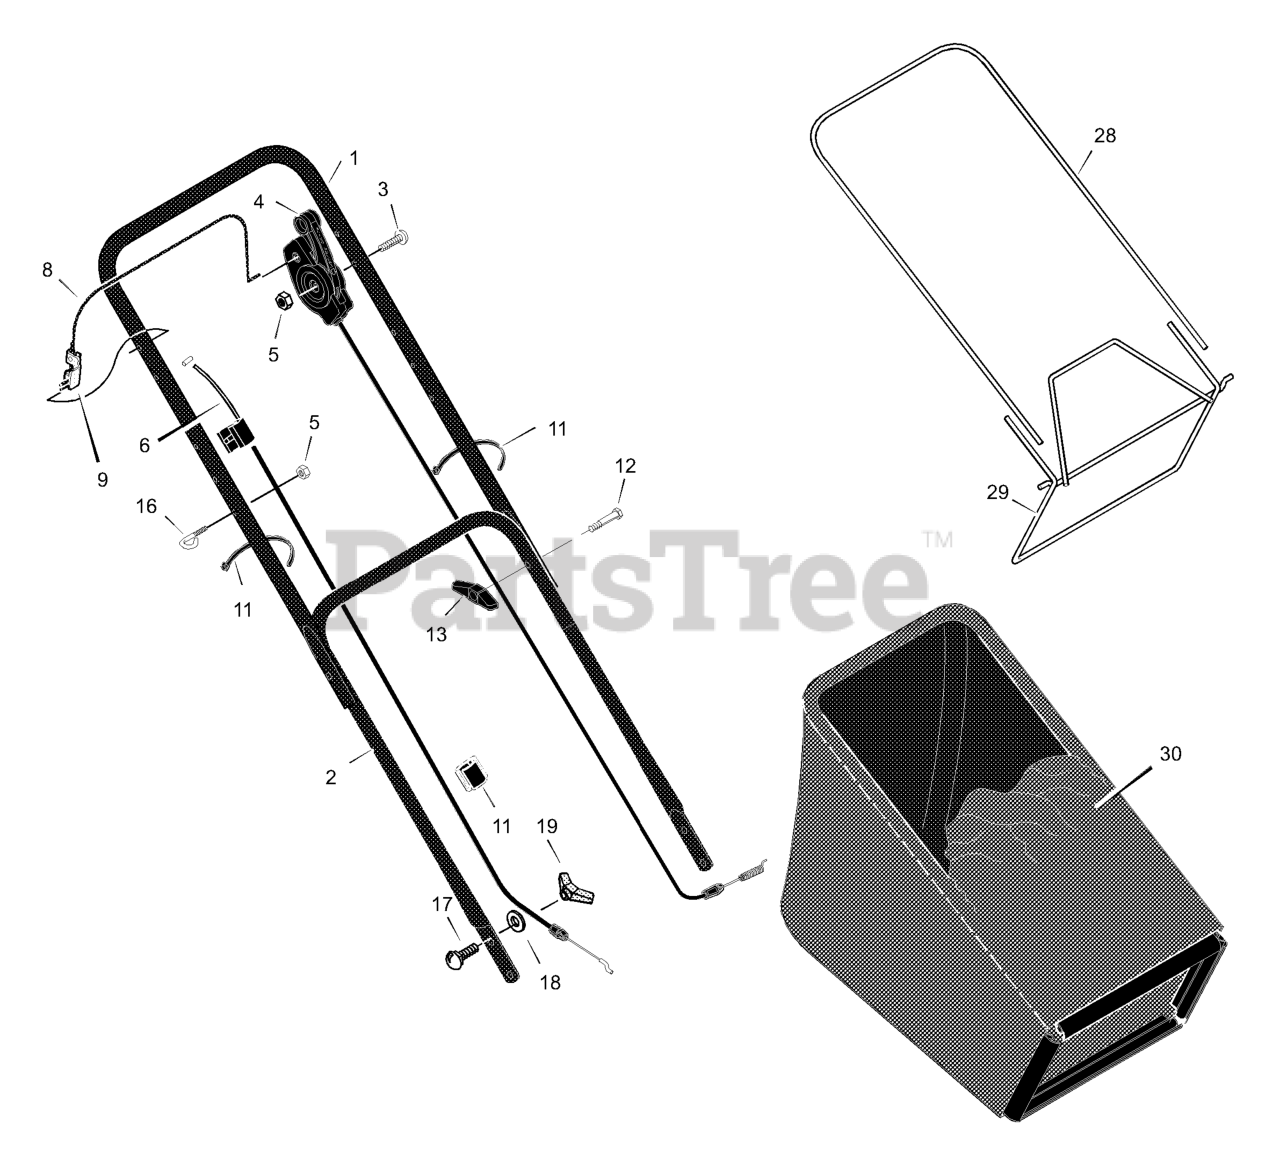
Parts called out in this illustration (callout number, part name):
1	Handle, Upper (Black)
2	Handle, Lower (Black)
4	Control, Drive
5	Locknut
6	Cable, Stop
8	Engine Stop Lever
9	Bracket, Stop Lever
11	Clip, Cable
13	Knob
16	Guide, Rope
17	Bolt, Carriage
19	Knob, Plastic
28	Frame, Top
29	Frame Assembly
30	Bag, Cloth
